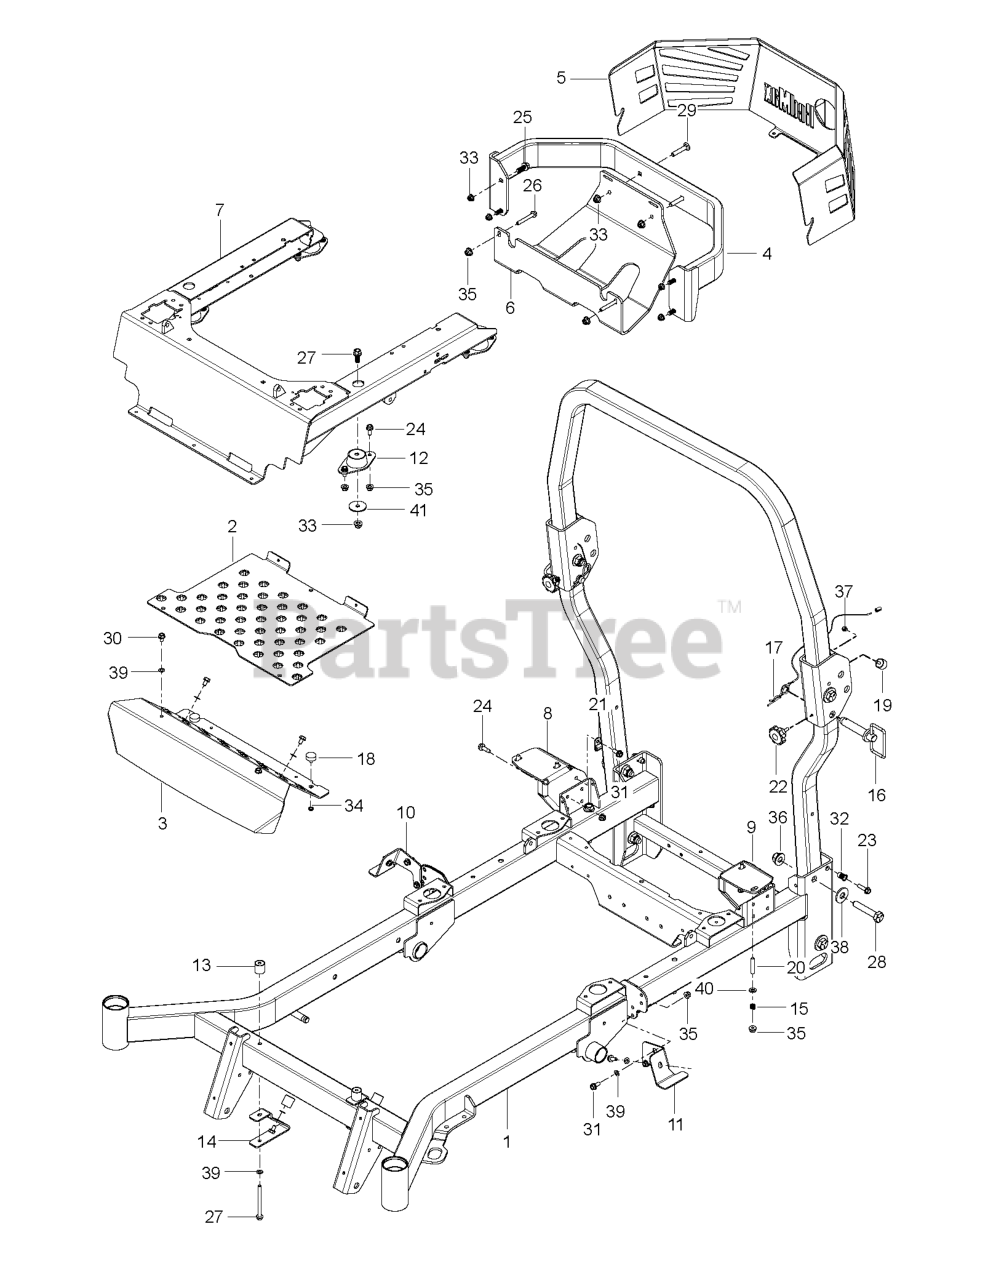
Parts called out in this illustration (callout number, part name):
1	FRAME.W/DECALS/CZT/REDMAX.672
2	PLATE FLOOR PAN SNAPPER RED X6
3	PLATE.FOOT.REST.BLACK
4	BUMPER REAR LONG SNAPPER RED X
5	GUARD REAR SNAPPER RED X672
6	PLATE, SKID, BLACK
7	FRAME SEAT MOUNT SNAPPER RED X
8	MOUNT, RT TANK, BLK
9	MOUNT, LT TANK, BLK
10	MOUNT, TANK, RT-BLK
11	MOUNT, TANK, LT-BLK
12	MOUNT, ISO
13	MOUNT, F/F INSERT
14	BRACKET, REST MOUNT
16	PIN.ROPS.W/HANDLE
17	PIN.HAIR.DOUBLE.LOOP.W/LANYARD
18	BUMPER, 1/4-20 STUD, 1/4
19	BUMPER, MALE STUD, 1/4-20
20	STUD, 5/16C
21	DOUBLE TUBE CLAMP
22	KNOB.5/16-18X1"BLACK
23	HHFS 5/16-18 X 1.25 TPBLT GD 5
24	HHFS 5/16-18 X 3/4
25	HHFS 3/8-16 X 1 GRD 5 ZD
26	HHFS 5/16-18 X 2.25 GD 5
27	HHFS 5/16-18 X 3 3/4
28	5/8-11 X 3-1/2 HHB GRADE 5
29	RHSNB 3/8C X 2
30	SCR 5/16-18 X 1/2 SELFTAP ZN
31	SCREW
32	NUTSERT 5/16-18 THICK GRIP
33	NUT 3/8-16 HEX FLG NYLOC ZD
34	JAM NUT 1/4C (2 2 PW01)
35	5/16-18 NYLOC FLANGE NUT
36	NUT 5/8-11 FLG NYLOC ZD
37	RP_NUT 1/4-20 NYLOC
38	WASHER, 5/8 FLAT
39	WASH 5/16 DISC SPRING ZD
40	WASHER
41	WASHER, 3/8 SPEC
